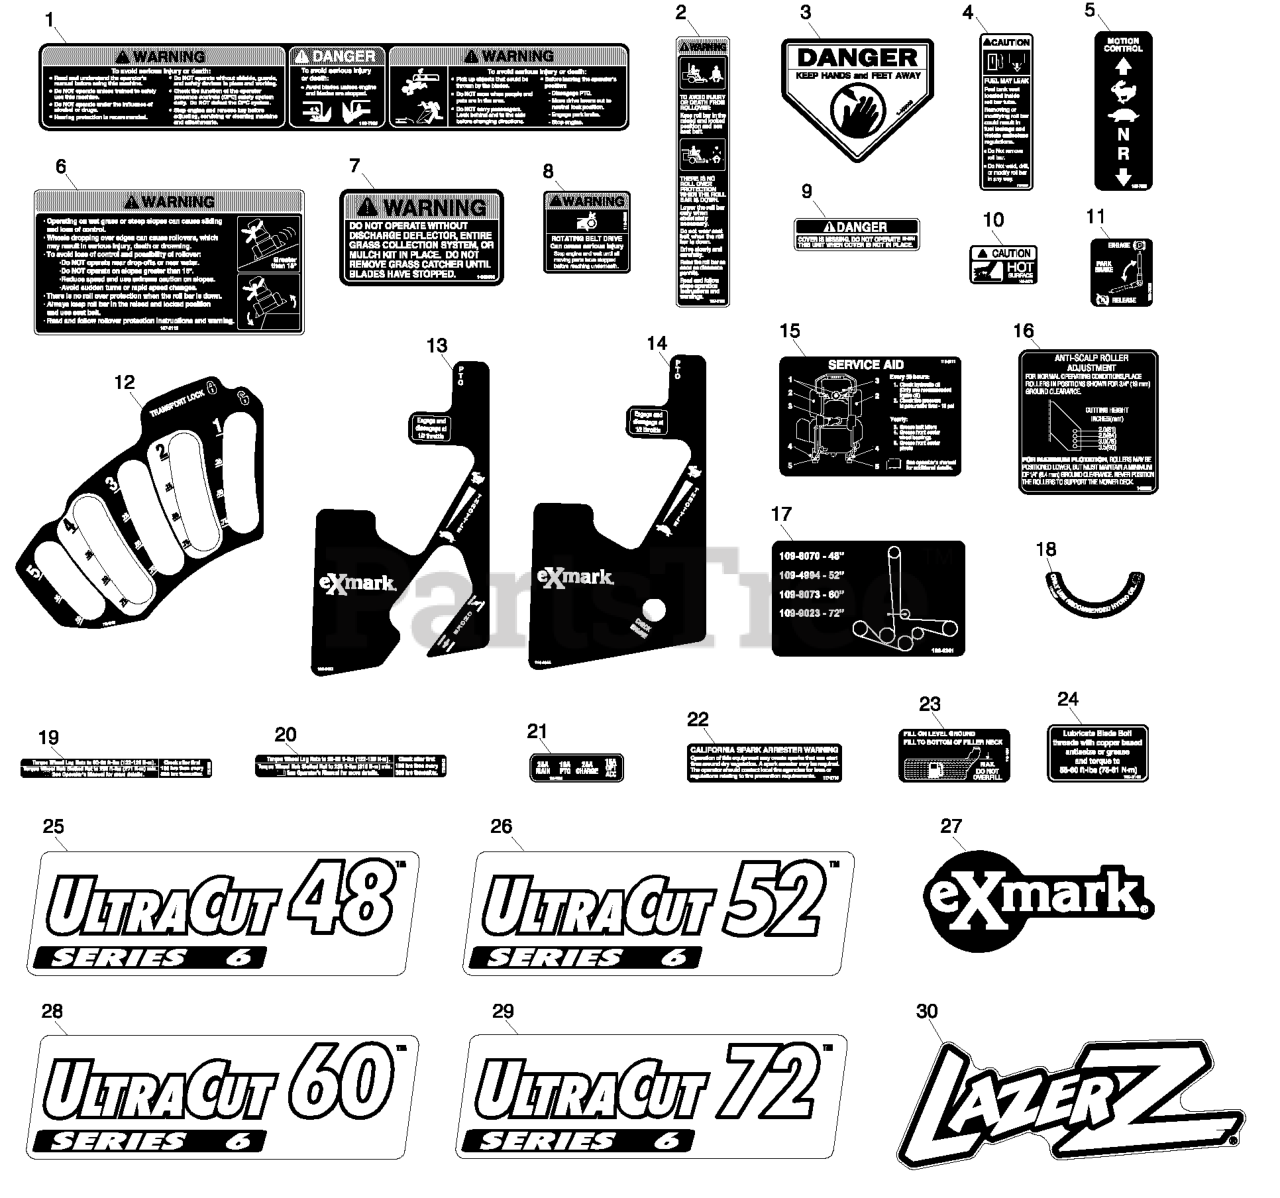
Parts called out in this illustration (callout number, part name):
1	DECAL-CONSOLE
2	DECAL-WARNING, FOLDING RO
3	DECAL-DANGER
4	DECAL-CAUTION
5	DECAL-MOTION CONTROL
6	DECAL-WARNING
7	DECAL-WARNING, DISCHARGE
8	DECAL-BELT DRIVE
9	DECAL-COVER, MISSING
10	DECAL-CAUTION
12	DECAL-HOC
13	DECAL-CONTROL PANEL
14	DECAL,CONTROL PANEL EFI
15	DECAL-SERVICE AID
16	DECAL,ANTISCALP
17	DECAL,BELT ROUTING
18	DECAL-HYDRO OIL
19	DECAL-HUB, WHEEL
21	DECAL-FUSE
22	DECAL-ARRESTER, SPARK
23	DECAL-FUEL FILL
24	DECAL,BOLT TORQUE
25	DECAL,ULTRACUT 48 SERIES
26	DECAL,ULTRACUT 52 SERIES
28	DECAL,ULTRACUT 60 SERIES
29	DECAL,ULTRACUT 72 SERIES
30	DECAL,LAZER MODEL
